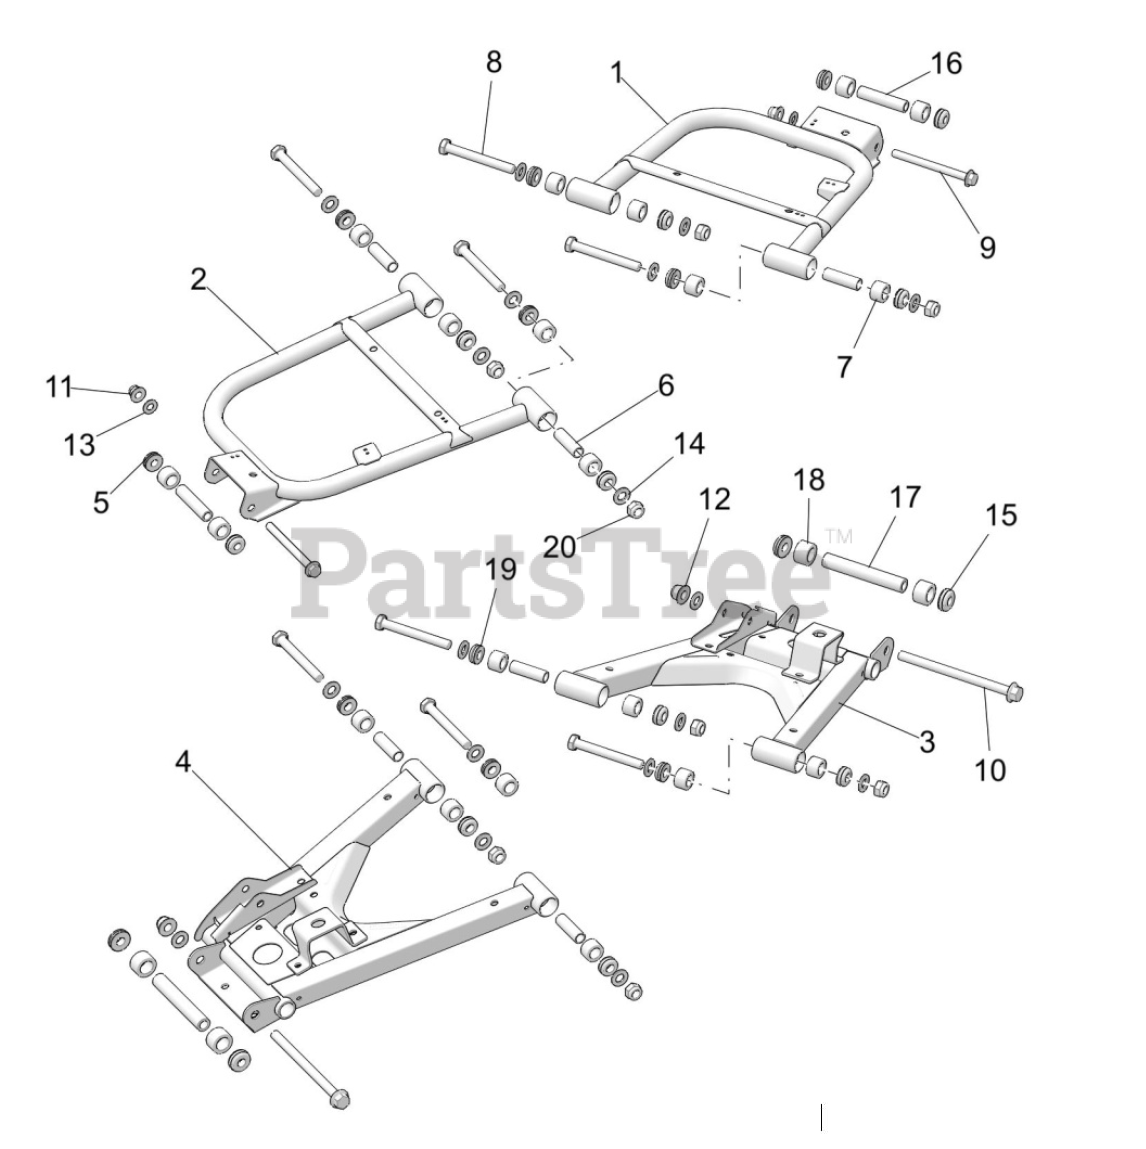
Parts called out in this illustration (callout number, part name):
1	WELD-CONTROL ARM,RR,UPR,LH,BLK
2	WELD-CONTROL ARM,RR,UPR,RH,BLK
3	WELD-CONTROL ARM,RR,LWR,LH,BLK
4	WELD-CONTROL ARM,RR,LWR,RH,BLK
5	ASM-PIVOT CAP,SEALED,M10
7	BUSHING-STANDARD,SUSP,M10
8	SCR-HH-M12X1.75X100 10.9 ZPC
9	SCR-HXFL-M10X1.25X115 10.9 ZOD
10	SCR-HXFL-M12X1.5X170 10.9 ZOD
11	NUT-M10X1.25,FLG,NYLOC-OLIVE D
12	NUT-M12X1.5,FLG,NYLOC-OLIVE D
13	WASHER,3/8 FW
14	WSHR-13.0X24.0X2.5 ZPC
15	ASM-PIVOT CAP,SEALED,M12
16	SHAFT-PIVOT,SHORT,M10
17	SHAFT-PIVOT,LONG,M12
18	BUSHING-STANDARD,SUSP,M12
19	ASM-PIVOT CAP,SEALED,M12
20	NUT-NYLOK,M12X1.5,0600110
